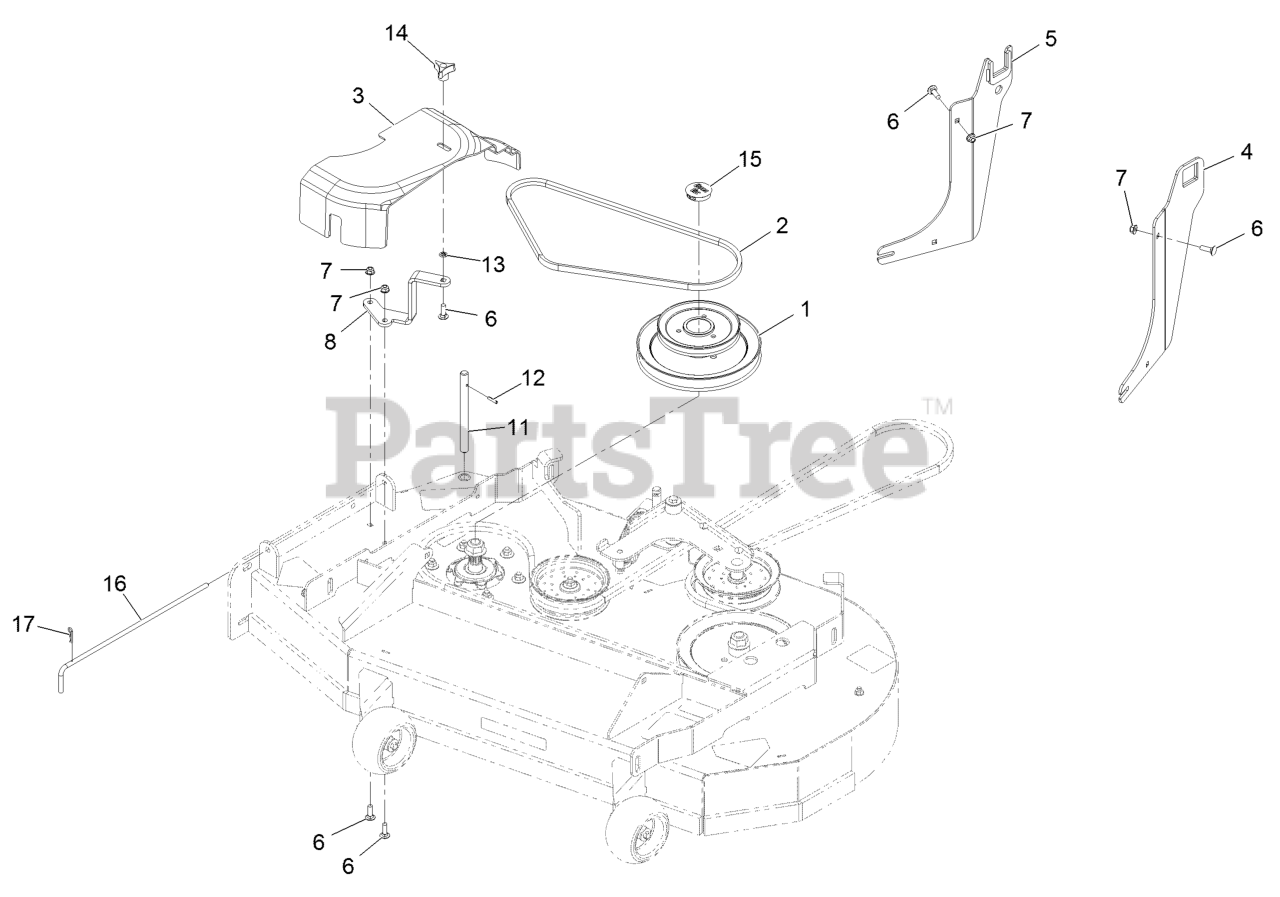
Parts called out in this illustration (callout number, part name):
1	JACKSHAFT,44 UV
2	BELT, BLOWER DRIVE 72
3	COVER-BELT, UV 44
4	BRACKET ASM, LH
5	BRACKET ASM, RH
6	BOLT-CARR
7	NUT-HF, NI
8	BRACKET-BELT COVER 44
11	SHAFT-CATCHER, GRASS
12	PIN-ROLL
13	RING-RETAINING, BOLT
14	KNOB-3 PRONG
15	PLUG, BLACK NYLON 1.75
16	PIN,CHUTE PIVOT
17	PIN-COTTER
